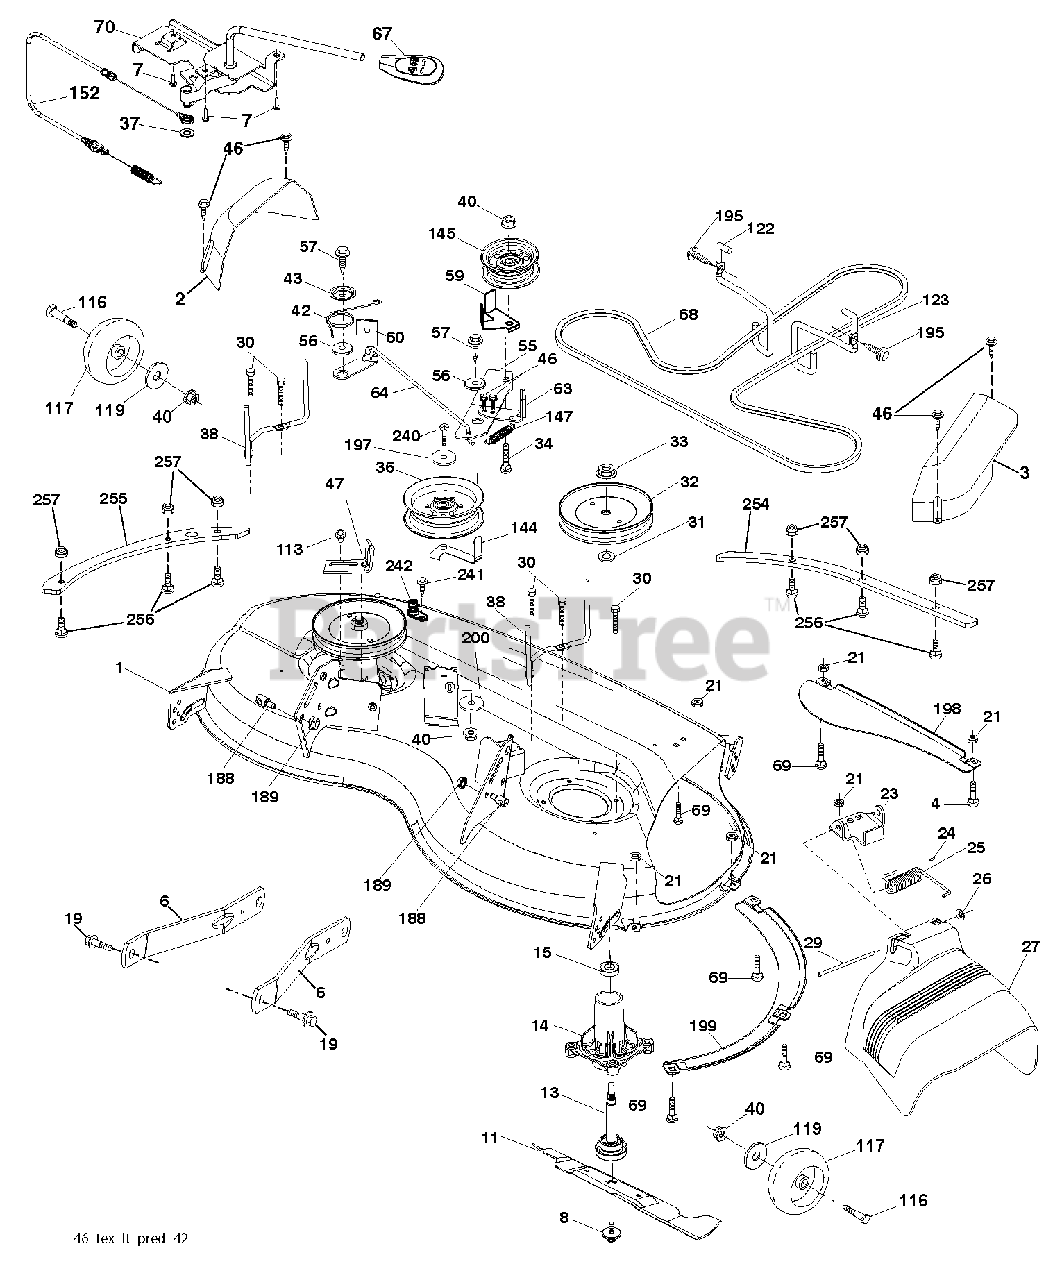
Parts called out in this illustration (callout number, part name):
1	DECK.SVC.46"441616X431
2	COVER.MANDREL.LH.46"
3	COVER.MANDREL.RH.46"
4	BOLT
6	ARM.SUSPENSION.MOWER.R
7	SCREW.#10 X 0.750.BOS
8	BOLT.WASHER.ASM.7/16-2
11	BLADE.MOWER.46".HI.LIFT
13	SHAFT.ASM.MDRL.N/GREASE.38
14	HOUSING.MANDREL.4PT.
19	BOLT.SHOULDER
21	LOCKNUT
23	BRKT.DEFLECTOR.38"2005+
24	CAP-SLEEVE LT
25	SPRING.TORSION.DEFLECT
26	NUT PUSH M
27	SHIELD.DEFLECTOR.MOWER.46"BLAC
29	ROD.HINGE
30	SCREW, WASHER HEAD
31	WASHER.SPACER.MANDREL
32	PULLEY.MANDREL.5.438.PD
33	NUT.FLANGE.LOCK.TOP
34	BOLT.3/8-16X1.50
36	PULLEY.IDLER.2006
37	WASHER
38	KEEPER.BELT.MANDREL.PULLEY
40	NUT LOCK FLG 3/8-16 UNC
42	SPRING.TORSION.BRAKE
43	SRPING.TORSION.RETAINE
46	SCREW.1/4-20X5/8
47	BRKT.CLUTCH.CABLE
56	SPACER.RETAINER
57	SCREW 3/8-16X1
59	GUARD, BELT
60	ARM BRAKE MOWER RH 38"
63	ARM BRAKE MOWER
64	LINKAGE BRAKE
67	HANDLE.CLUTCH.CABLE.LT
68	V-BELT
69	BOLT
70	CLUTCH.ASM.MANUAL.YT.PREDATORQ
113	BOLT.5/16HEX.WHS.HD
116	BOLT.SHOULDER.3/8-16X3-5/8.
117	WHEEL. GUAGE RALLY
119	WASHER
122	KEEPER BELT ENGINE LH
123	KEEPER BELT RH
144	KEEPER.BELT.MOWER
145	PULLEY.IDLER.48"PRIMARY
147	SPRING RETURN
152	CABLE.MECHANICAL.CLUTCH
188	STUD.FASTNER.W/ANTI-ROTATE
189	NUT LOCK HEX FLANGE 5/16-18
195	SCREW, 3/8-16X3/4
197	WASHER
198	BAFFLE CENTER FRONT
199	BAFFLE FRONT RH
200	WASHER.13/32 X 1 X 1/2.11GUARD
240	BOLT-HEX EAK
241	SCREW.TT.#10-32X.5.3/8.FLANGE
242	PORT.WASHOUT
254	PLATE.RNFRCMENT.46.FRONT X431
255	PLATE.RFORCRMRNT.46.SIDE X431
256	SCREW.BUTTONHEAD.1/4-20X1
257	NUT T
